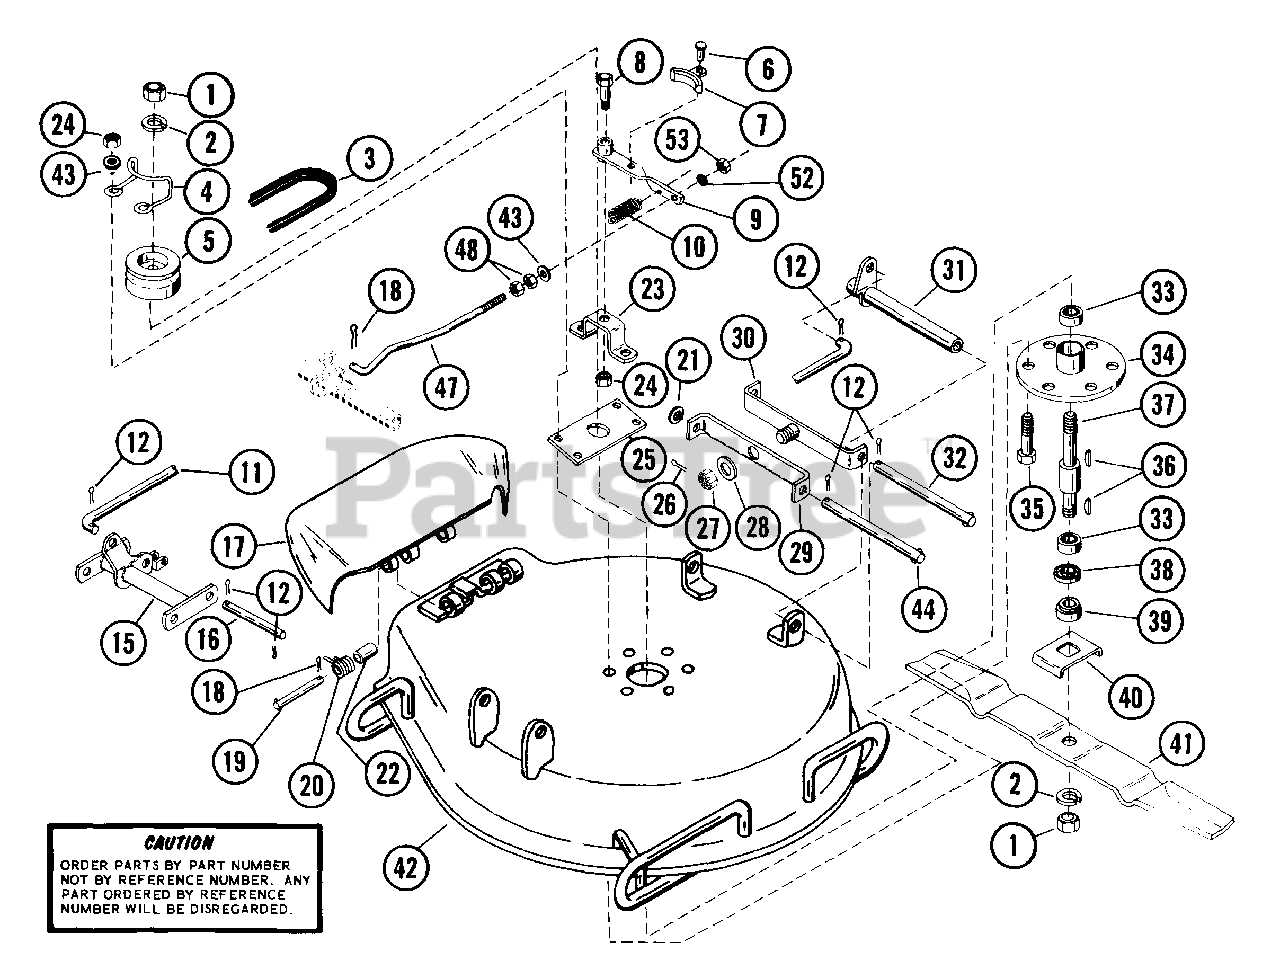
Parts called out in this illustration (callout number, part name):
1	NUT-JAM .75-10 PL
2	WSHR-LK .750X.188 MED PL
3	V-BELT, 5L-RAW EDGE
4	MOWER BELT FINGER
5	MOWER SHEAVE
6	RVT .25X.50 RH ST
7	BLADE BRAKE
8	SHOULDER BOLT .50 X 1.75
9	BRAKE ARM
10	SG-TENS .072X.51X5.31 WLD 25
11	HEIGHT LINK ROD
12	PIN-COTR .12X1.0 PL
15	PAN HEIGHT BRACKET
16	ADAPTER PIN
17	PAN CHUTE EXTENSION
18	PIN-COTR .09X.75 PL
19	CLEVIS PIN
20	SG-TORS .095X.50X 1.0
21	WSHR-FL-STL .531X1.062X.095 PL
22	BSHG-SLV .334 X .502 X 1.437
23	BLADE BRAKE SUPPORT
24	NUT-LK-CTR .375-16 GR A PL
26	PIN-COTR .12 X 1.25 PL
27	NUT-JAM-SL .625-18
28	WSHR-FL-STL .630X1.005X.062 PL
31	REAR RAISING BRACKET
32	REAR BRACKET PIN
33	BRG-BALL .751X1.78X.61
34	SPINDLE HOUSING
35	BLT-HEX .38-16X1.00 PL
36	KEY-WDRF .188X.75X.313 SAE 9
37	MOWER SPINDLE
38	BEARING SLINGER
39	RETAINER HUB
40	BLADE TRAY
41	BLADE, MOWER
42	MOWER PAN ASSEMBLY
43	WSHR-FL-STL .38X.875X.083 PL
44	HANGER PIN
47	BLADE BRAKE ROD
48	NUT-HEX .312-18
52	GROMMET
53	NUT-LK .312-18 GR A PL
